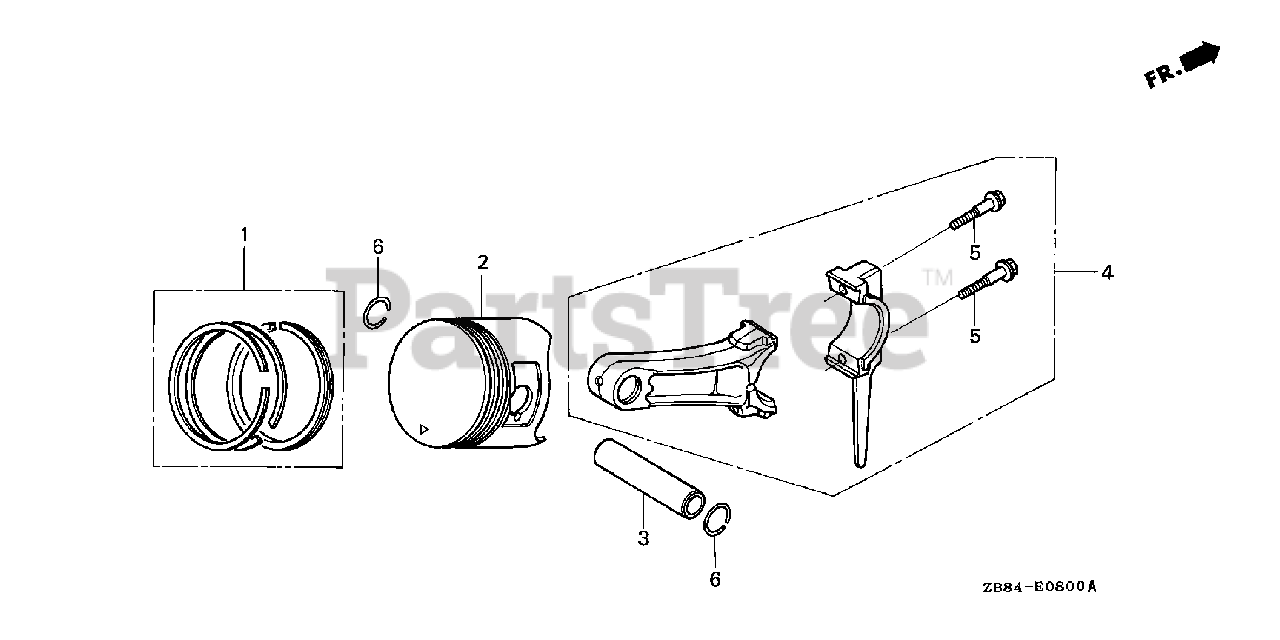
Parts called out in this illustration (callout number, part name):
1	RING SET, PISTON (STD)
1	RING SET, PISTON (OS 0.25)
1	RING SET, PISTON (OS 0.50)
1	RING SET, PISTON (0.75)
2	PISTON (STD)
2	PISTON (OS 0.25)
2	PISTON (OS 0.50)
2	PISTON (0.75)
3	PIN, PISTON
4	ROD ASSY., CONNECTING (STD)
4	ROD ASSY., CONNECTING (0.25 LOWER SIZE)
5	BOLT, CONNECTING ROD
6	CLIP, PISTON PIN (20MM)
